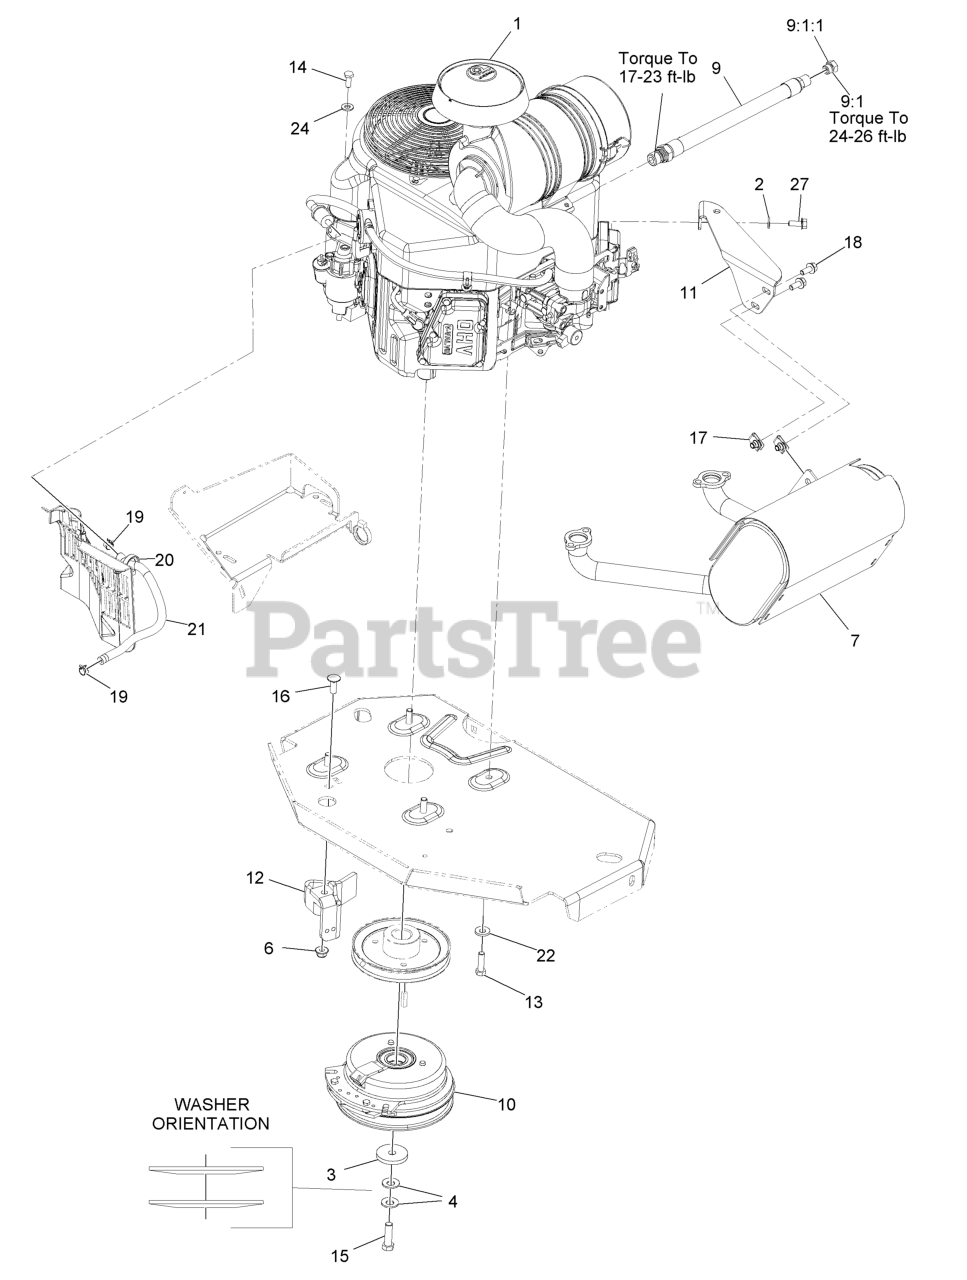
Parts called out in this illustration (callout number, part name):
2	WASHER-SPRING
3	WASHER-CLUTCH
4	WASHER-SPRING
6	NUT-HF, NI
7	MUFFLER
9	ENGINE OIL DRAIN HOSE ASM
9:1	PLUG-HH
9:1:1	O-RING
10	CLUTCH KIT
11	BRACKET-MUFFLER
12	CLUTCH-ANCHOR
13	SCREW-HH
14	SCREW-HH
15	SCREW-HH 7/16-20 X 1 1/2 W/LOCTITE
16	SCREW-CARR
18	SCREW-HHF
19	CLAMP-HOSE
20	CLAMP-HOSE
21	HOSE-FUEL
22	WASHER-BELLEVILLE
24	WASHER-PLAIN
27	SCREW-HHF
